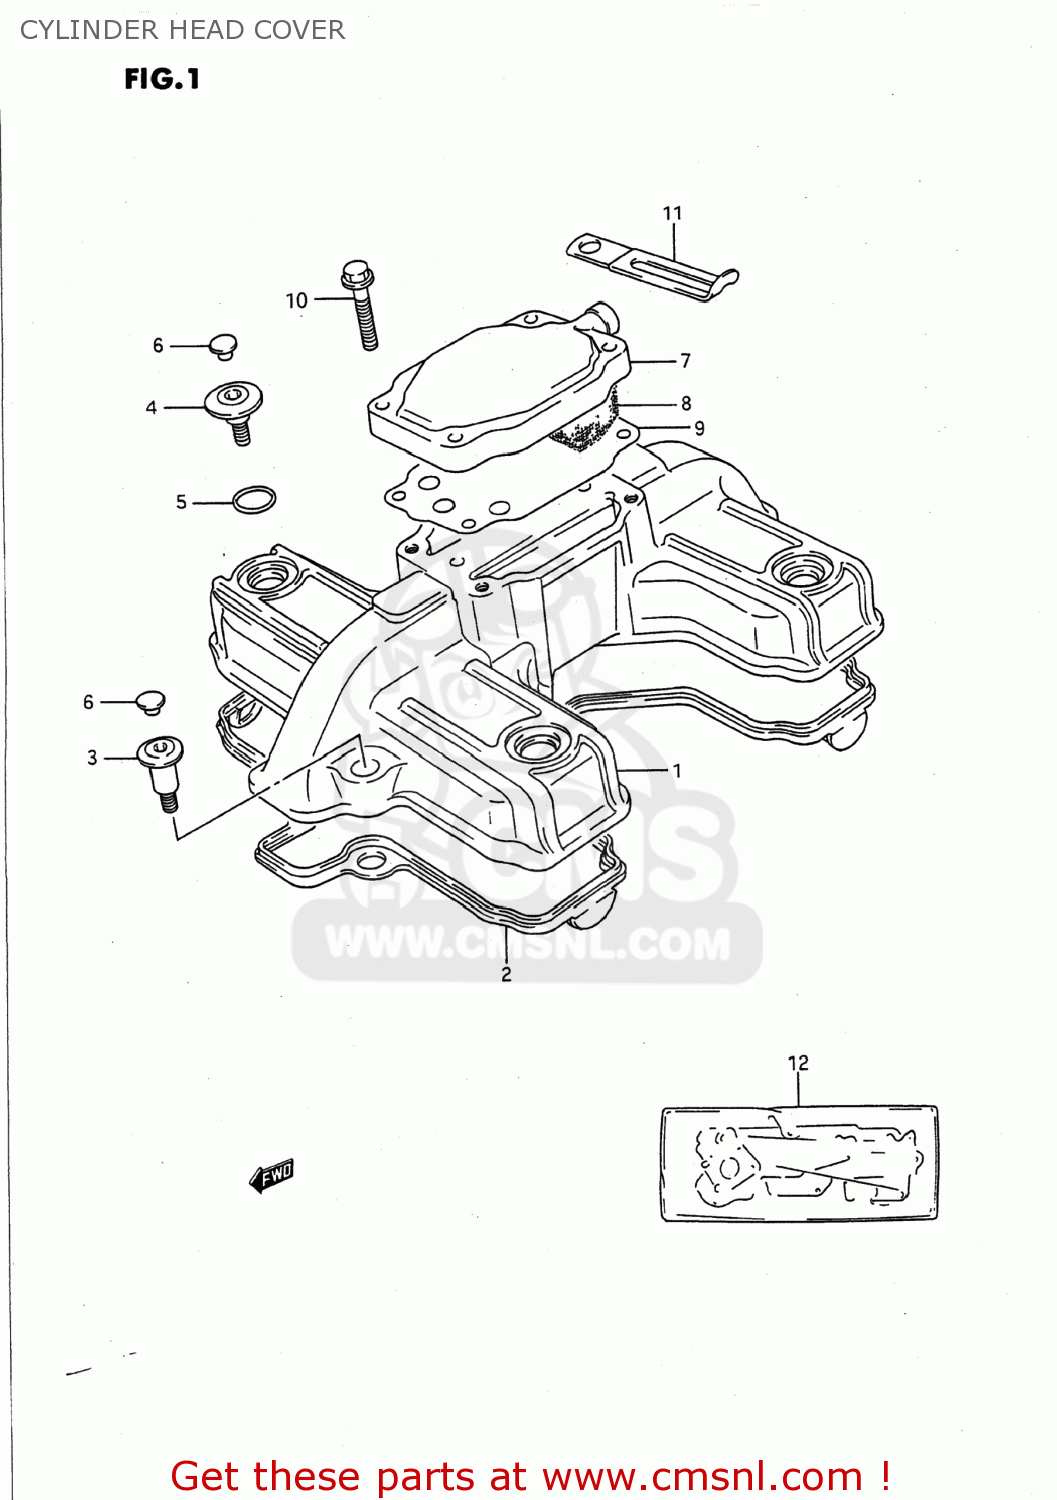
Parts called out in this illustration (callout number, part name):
1	COVER,CYLINDER HEAD
2	GASKET,CYLINDER HEAD COVER (NAS)
3	BOLT(7X19)
4	BOLT(7X5.5)
5	O RING(D:1.9,ID:14.5)
6	CAP(OD:10)
7	COVER,BREATHER
8	SEPARATOR,OIL BREATHER CO
9	GASKET (NAS)
10	BOLT
11	CLAMP
12	GASKET SET (NAS)
